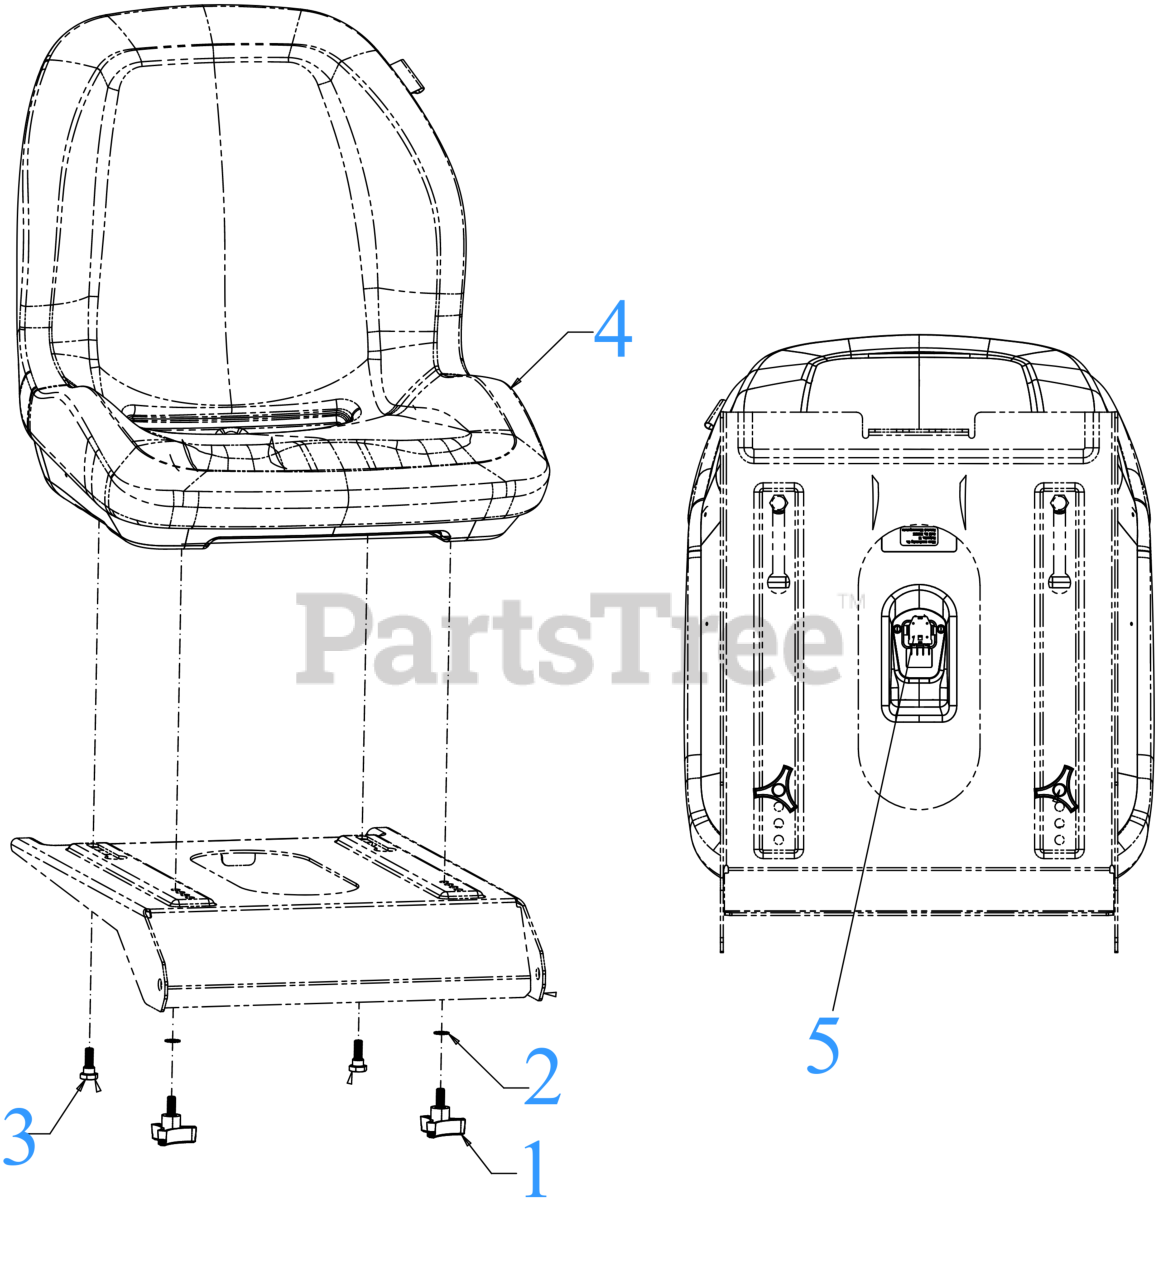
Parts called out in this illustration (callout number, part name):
1	3 PRONG KNOB 5/16-18
3	SHOULDER SCREW .437
4	18" SEAT (4 PT MT)
5	SEAT SWITCH (NC/NO)
